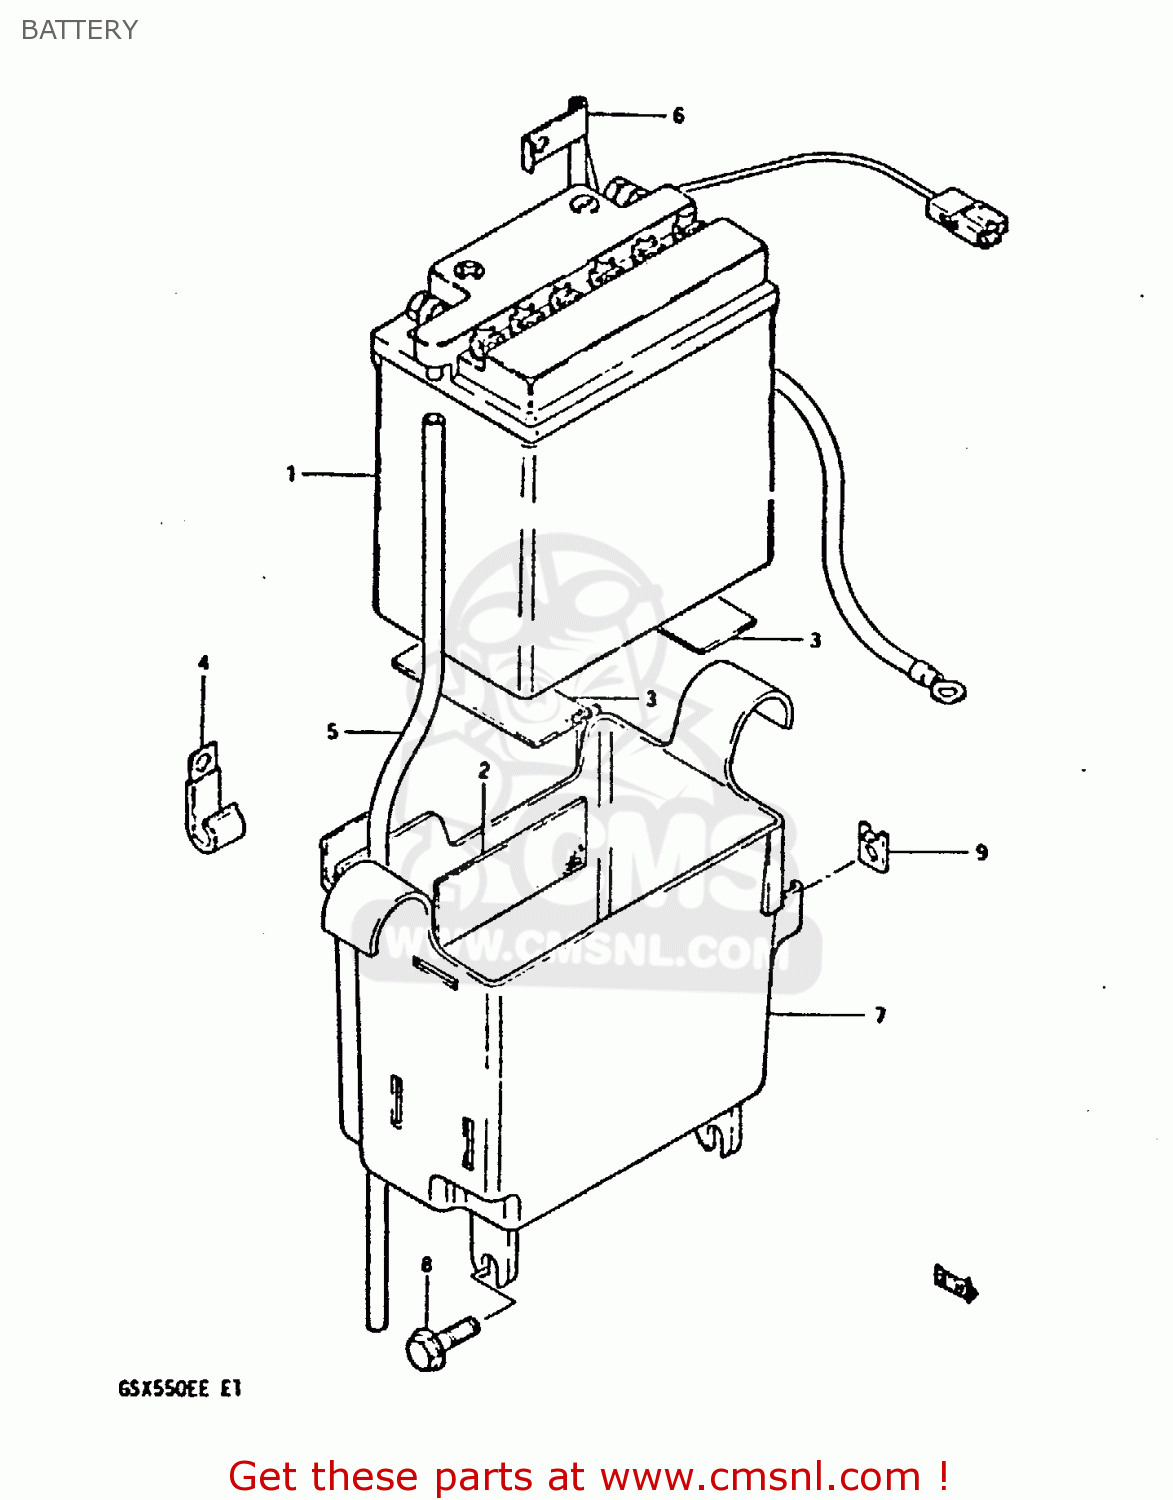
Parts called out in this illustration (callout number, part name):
1	BATTERY(YB10L-B,12V12AH)
2	PROTECTOR(30X80X2)
3	PROTECTOR,20X9
4	CLAMP
5	HOSE,BATTERY EXHAUST
6	WIRE,STARTER MOTOR LEAD
7	HOLDER,BATTERY
8	BOLT
9	WASHER,IGNITER
